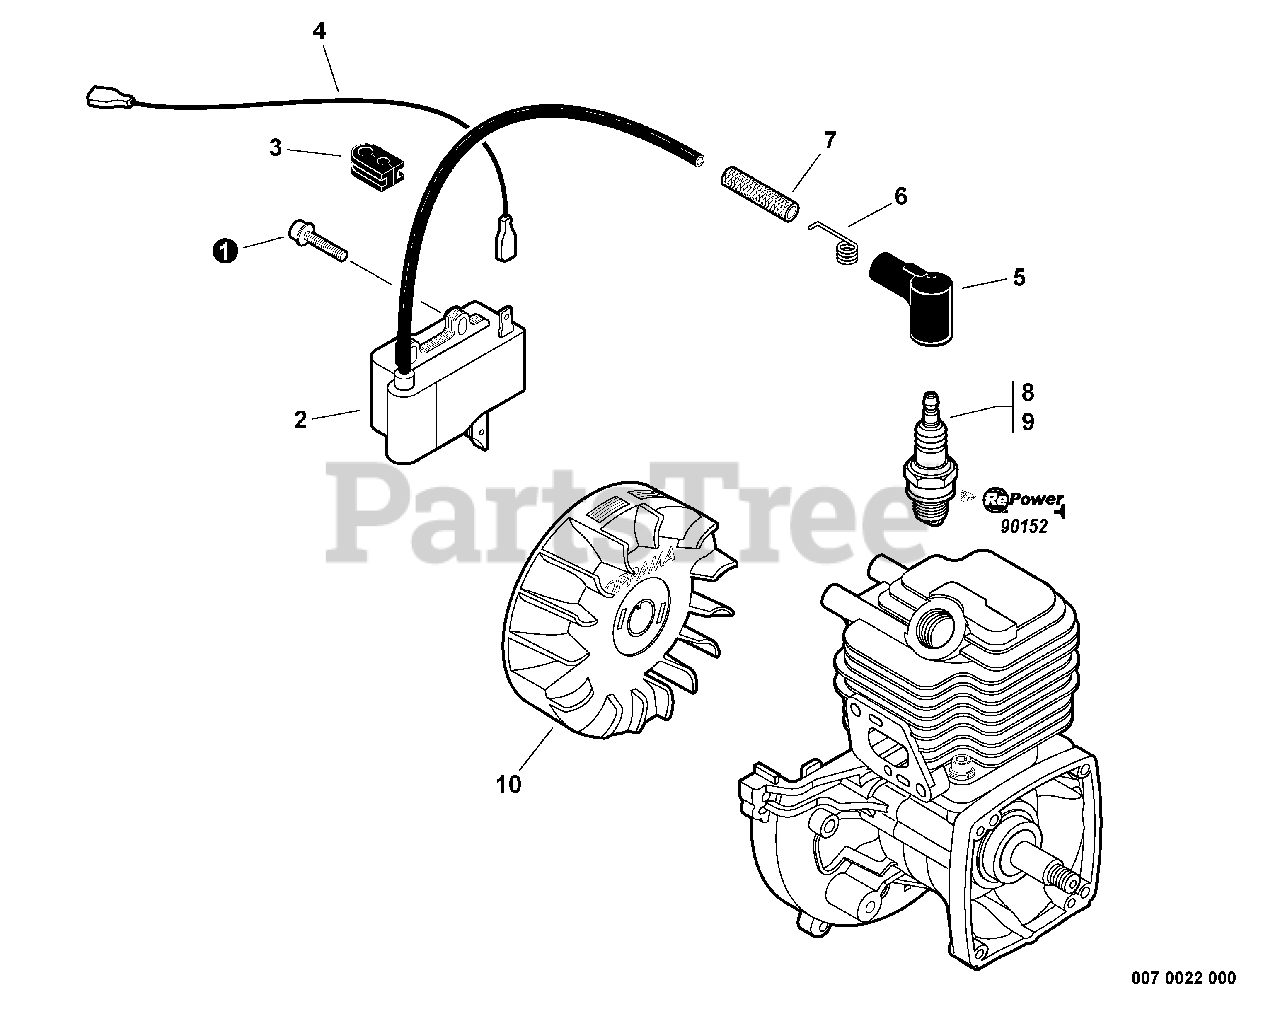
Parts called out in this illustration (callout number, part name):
1	SCREW - 4X20
2	COIL, IGNITION
4	LEAD - IGNITION
5	CAP, SPARK PLUG
6	TERMINAL, SPARK PLUG CAP
7	TUBE, INSULATOR
8	SPARK PLUG -- BPM-8Y
9	SPARK PLUG -- BPMR-8Y
10	FLYWHEEL
11	Repower TUNE-UP KIT
